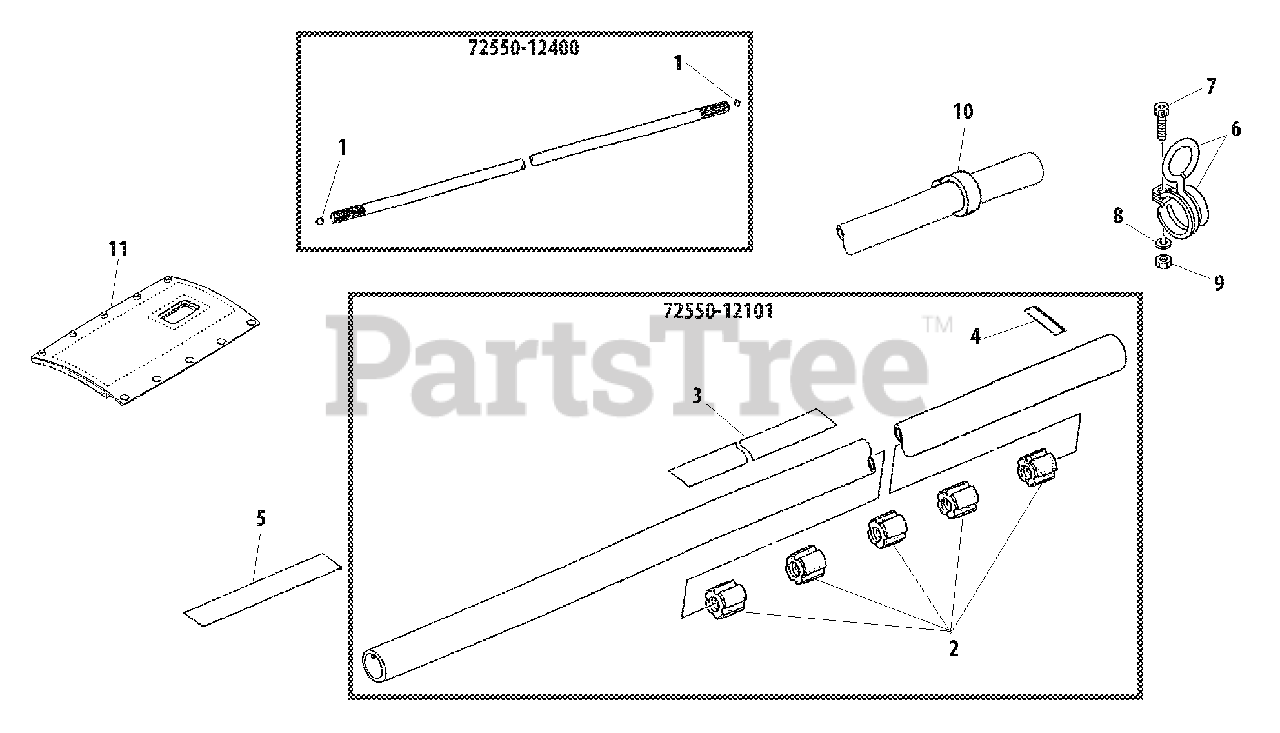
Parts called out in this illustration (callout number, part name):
1	STOPPER
2	BUSHING
3	LABEL - MODEL
4	LABEL - ALIGNMENT
5	LABEL, CAUTION
6	HANGER
7	BOLT 5×12
8	WASHER, SPRING 5
9	NUT M5
10	HOLDER, CABLE
11	PROTECTOR
72550-12101	MAIN PIPE ASSY
72550-12400	DRIVESHAFT ASSY
